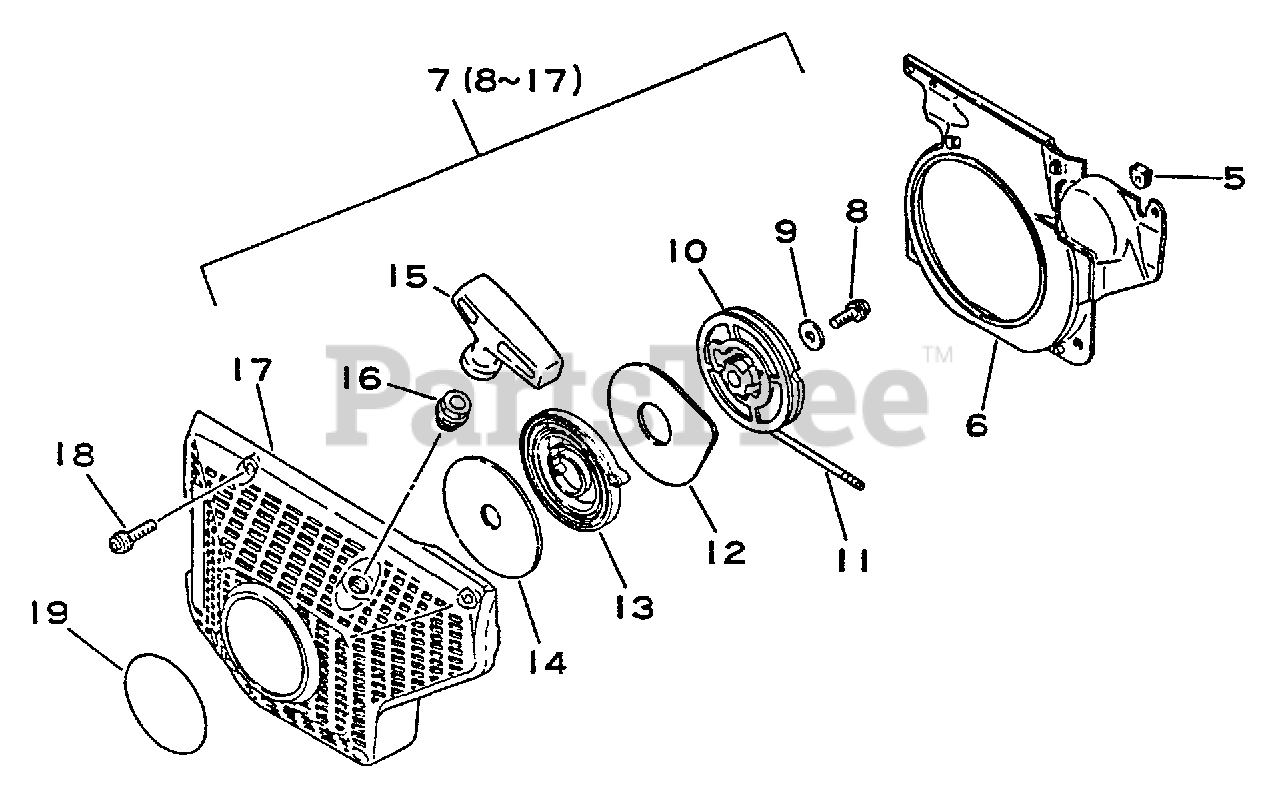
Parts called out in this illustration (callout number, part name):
6	SHIELD, FAN
7	STARTER ASSY
8	SCREW - 5X14
9	WASHER - 5
10	REEL, ROPE
11	ROPE, STARTER - 3.5X960
12	PLATE, STARTER
13	SPRING, REWIND
14	PLATE, STARTER
15	GRIP, STARTER
16	GUIDE, ROPE
17	CASE, STARTER
18	SCREW - 5X20
19	LABEL - ECHO
